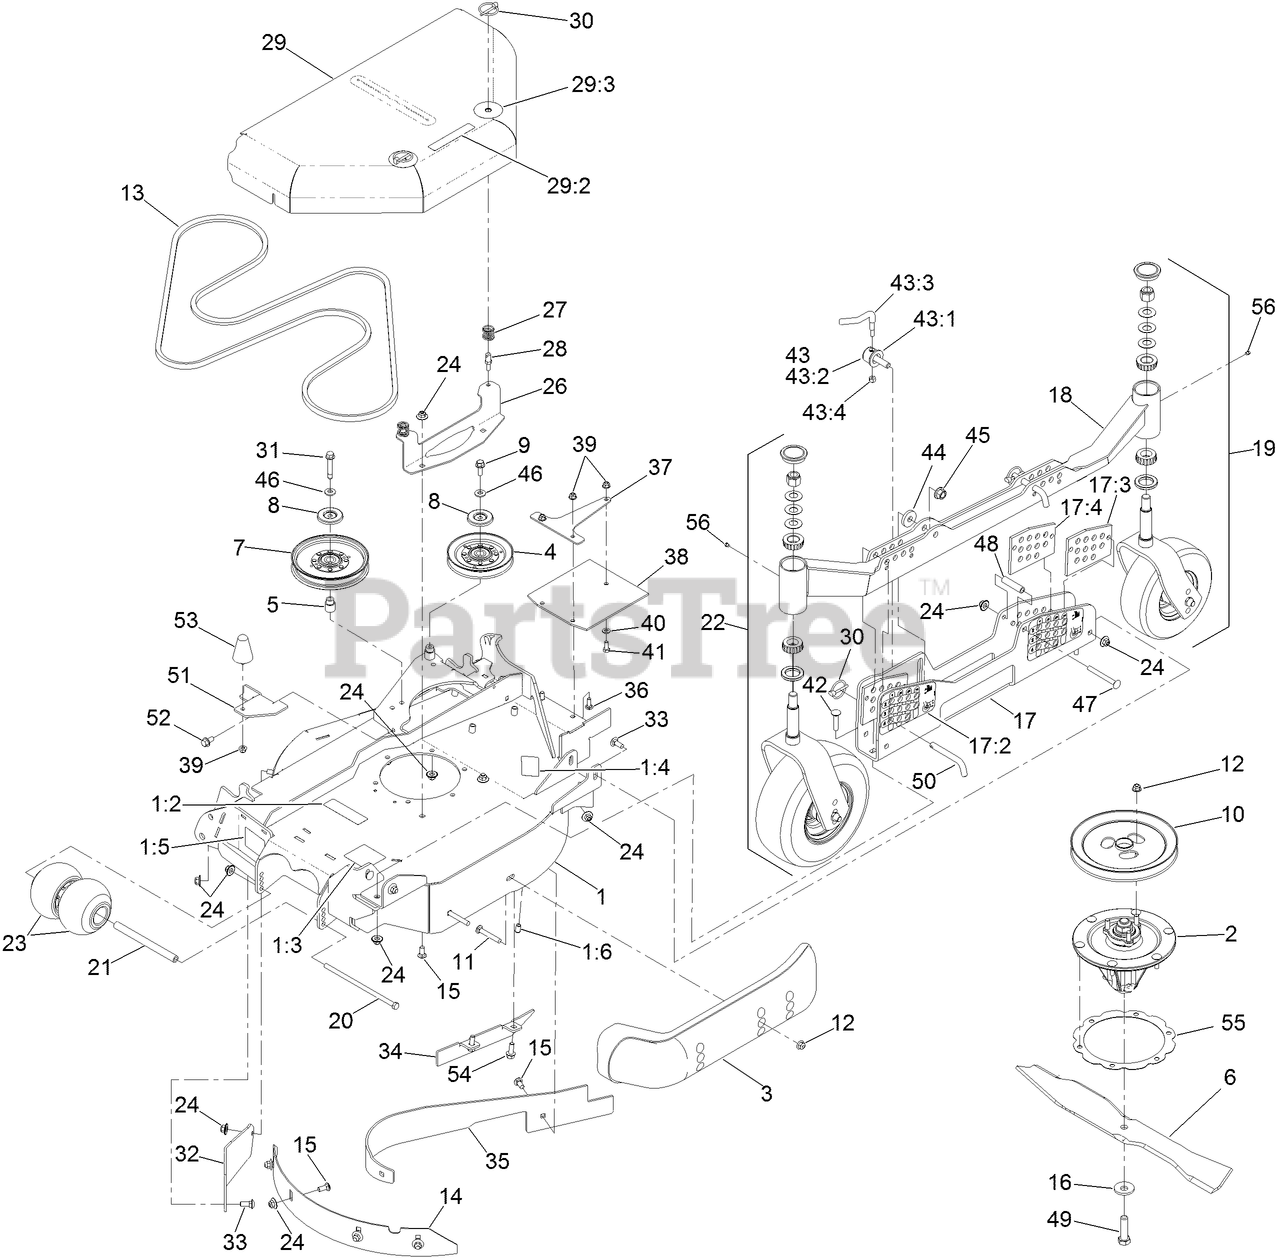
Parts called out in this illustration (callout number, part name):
1	LH WING DECK DECAL ASM
1:2	DECAL-COVER, MISSING
1:3	DECAL-DANGER, THROWN OBJECT
1:4	DECAL-BOLT TORQUE
1:5	DECAL-WARNING, PINCH POINT
1:6	NUT-CLINCH
2	SPINDLE ASM
3	SKID-BUMPER, DECK
4	IDLER-V
5	BUSHING-IDLER
6	BLADE-MULCH, 24.5IN
7	IDLER-PULLEY
8	SHIELD-DUST
9	SCREW-HHF
10	SHEAVE-SINGLE 96 RD (TORO)
11	SCREW-CARR
12	NUT-HF, NI
13	BELT-V
14	BAFFLE-DEPTH, LH
15	BOLT-CARR
16	WASHER-BLADE BOLT, HEAVY
17	LH HOC CHANNEL ASM
17:2	DECAL-HEIGHT OF CUT-LH
17:3	PLATE-GUIDE, HOC (LH)
17:4	PLATE-GUIDE, HOC (RH)
18	TUBE-HOC, LH
19	REAR CASTER WHEEL ASM
20	SCREW-HH
21	SPACER-WHEEL
22	CASTER WHEEL ASM
23	ROLLER-SCALP, ANTI
24	NUT-FLANGE, NI
26	BRACKET-SHIELD MOUNT, OUTER
27	SPRING
28	PIN-SPRING
29	LH WING SHIELD ASM
29:2	DECAL-NO STEP
29:3	DECAL-SCRATCH COVER
30	PIN-LYNCH
31	SCREW-HHF W/ PATCH
32	PLATE-FILL, LH DECK
33	SCREW-HH
34	FIN-BAFFLE, DISCHARGE WING (LH)
35	BAFFLE-DOGLEG, CENTER (RH)
36	SCREW-CARR
37	SUPPORT-FLAP, LH
38	GUARD-TIRE, LH
39	NUT-HF, NI
40	WASHER-PLAIN
41	SCREW-HH
42	SCREW-HH
43	LEVER ASM
43:1	SCREW-LOCK
43:2	CAP-LOCK
43:4	NUT-LOCK, NI
44	WASHER
45	NUT-LOCK
46	WASHER-BELLEVILLE
47	SCREW-CARR
48	SPACER
49	SCREW-BLADE
50	PIN-HOC
51	BRACKET-COVER RETAINER
52	SCREW-HWH
53	BUMPER-RUBBER
54	SCREW-HHF
55	RING-SPACER, HOUSING
